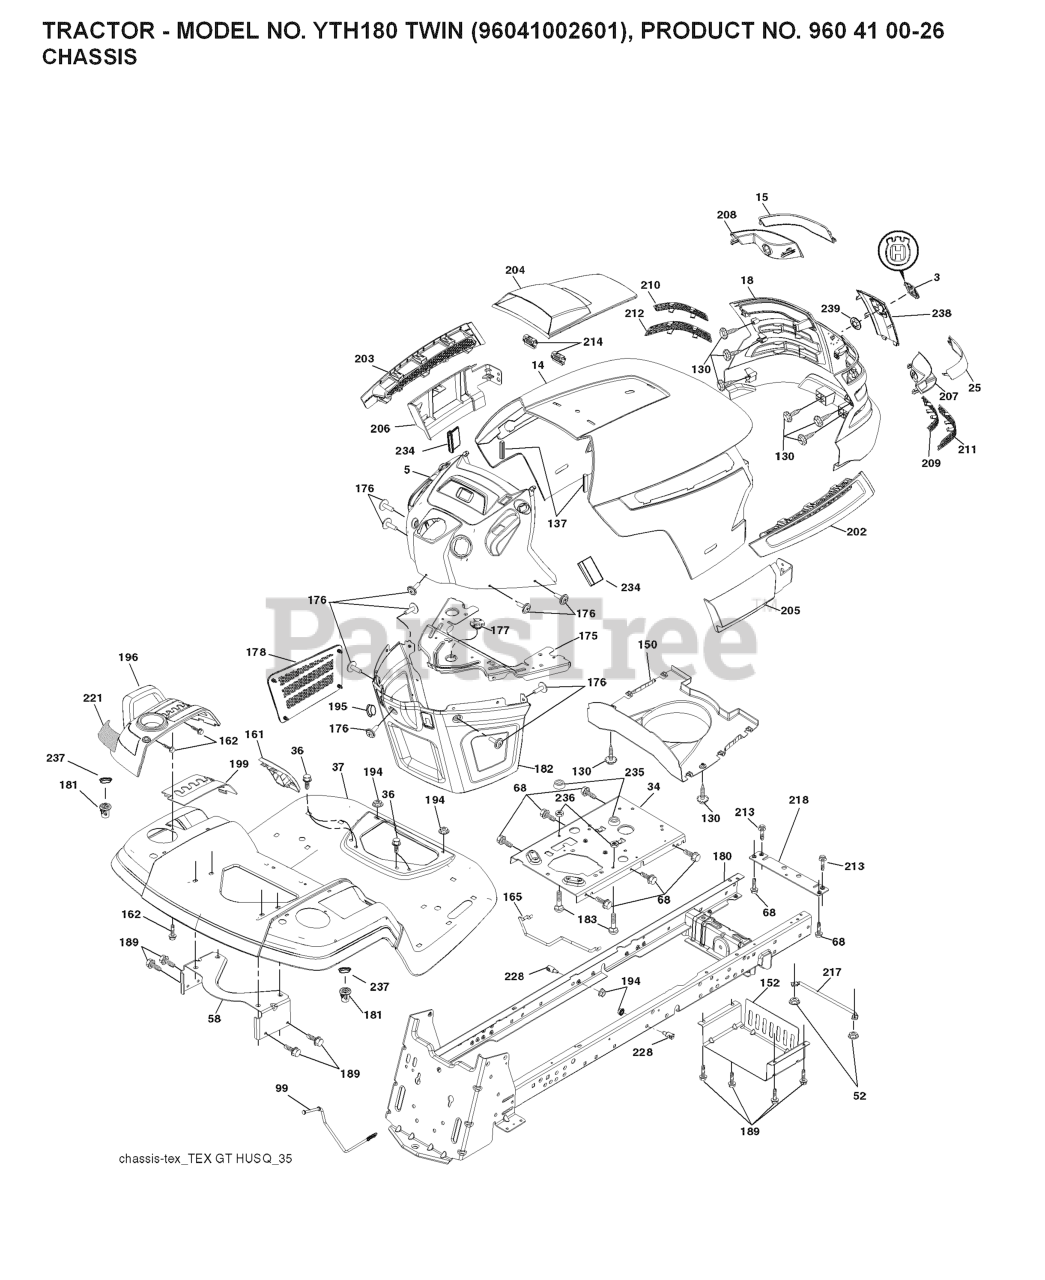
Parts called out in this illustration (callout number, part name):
3	RP LOGO
5	DASH.ASM.HUSQ.GT.E.RECT.W/CK
14	HOOD
15	LENS.LH.TEX.GT.HUSQ.CL
18	GRILL.ASM.HUSQ.TG/CRD.W/TRIM
25	LENS.RH.TEX.GT.HUSQ.CL
34	PLATE.ENGINE.WELDED.CHASSIS
36	SCREW 5/16"
37	FENDER.PNT.TX.GT.CH/FW.ORANGE
52	LOCKNUT
58	BRKT.SUPPORT.FNDR/TANK
68	Screw 5/16-18 x 1/2 Hex, Self Tapping 5/16-18 x 1/2
99	ROD.BYPASS.HYDRO.0510/0610.GT
130	SCREW
137	BUMPER DASH
150	AIR.DUCT.HOOD.TEX.GT.HUSQ
152	SHIELD.BROWNING.W/TEX
161	CONSOLE.FUEL.WINDOW.HU
162	SCREW.HI-LO.CONSOLE
165	SUPPORT.TANK.REAR.W/TEX
175	PLATE.CROSSMEMBER.HUSQ
176	SCREW.#10-24X5/8.RN.QU
177	BUSHING, STEERING
178	CARGO.ASM.NET.TXGT.W/C
180	CHASSIS.GT.SLOPED.DRAWBAR.
181	BUSHING.MNT.FEND.CRGO.
182	DASH.LOWER.COMMON.12V.
183	BOLT.5/16-18X1-1/4 FULL.THREAD
189	SCREW
194	NUT LOCK HEX FLANGE 5/16-18
195	PLUG.HOLE.DASH.LOWER.12V.BLK
196	RP CONSOLE.ASM.DECKLFT.W/
199	PLATE.DECK.LIFT.HUSQVARNA.GT
202	VENT.SIDE.HOOD.HUSQ.RH.GREY
203	VENT.SIDE.HOOD.HUSQ.LH.GRAY
204	VENT.TOP.HOOD.HUSQVARN
205	SKIRT.HOOD.SIDE.HUSQ.RH.GREY
206	SKIRT.HOOD.SIDE.HUSQ.LH.GREY
207	BEZEL.RH.TEX.GT.HUSQ
208	BEZEL.LH.TEX.GT.HUSQ
209	INSERT.HEX.GRILL.HUSQ.GREY
210	INSERT.HEX.GRILL.HUSQ.
211	INSERT.HEX.GRILL.HUSQ.
212	INSERT.HEX.GRILL.HUSQ.
213	BOLT
214	CLIP.RETAINER.TINNER.
217	ROD.PIVOT.HOOD
218	X-PIECE.HOOD.STOP.NON/
221	REFLECTOR.LH.TEX GT HU
228	STUD.FASTNER.W/ANTI-ROTATE
234	BUMPER.HOOD.TEX.HUSQVARNA
235	SPACER FENDER
236	NUT.CENTERLOCK.5/16-
237	PLUG.MOUNT.CARGO.BLK
238	TRIM.HUSQ.TG/CRD.SERVICE
239	NUT PUSH M
243	BUMPER.HOOD.TEX.HUSQVARNA
